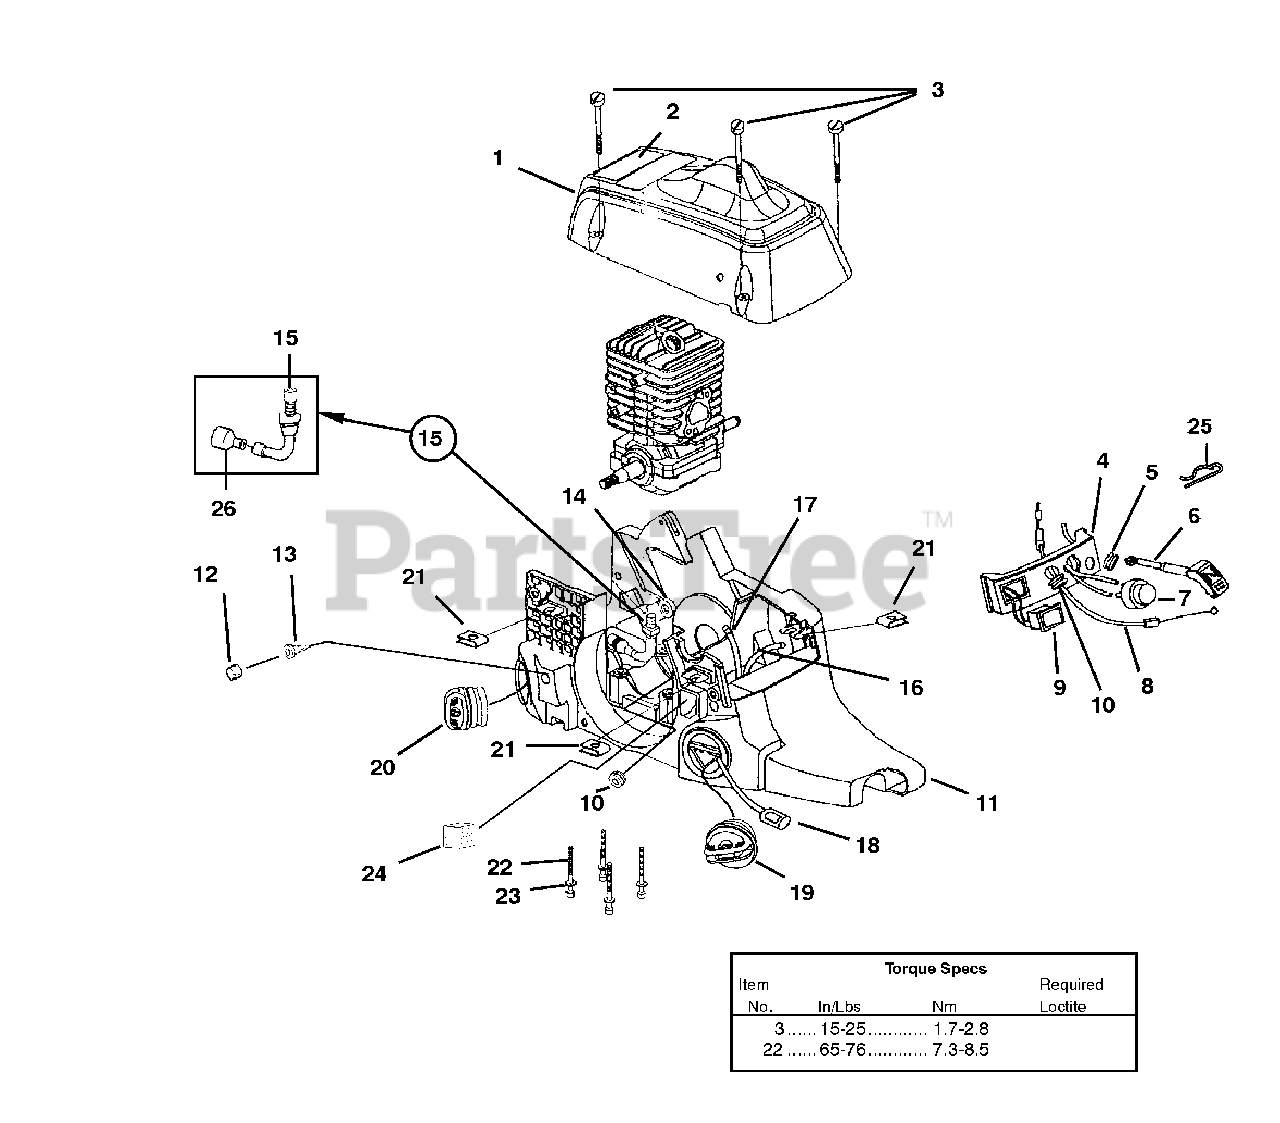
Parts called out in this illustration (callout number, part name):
1	Cylinder Cover Kit
2	Safety Decal
3	Screw-Slotted Pan Hd.
4	Control Panel
5	Grommet
6	Rod, Choke
7	Bulb, Air Purge
8	Throttle Cable
9	Switch, Rocker
10	Grommet - Split
11	Engine Housing
12	Element, Filter (Bronze)
13	Duck Bill Valve
14	Oil Outlet Grommet
15	Oil Intake Tube
16	Rubber Tubing (5 1/2")
17	Rubber Tubing (8 1/2")
18	Fuel Filter
19	Fuel Cap w/ Retainer
20	Oil Cap w/ Retainer
21	Speed Nut ("U-Type")
22	Screw, Cap-Socket Hd. (10-24 x 2")
23	Washer
24	Pre Filter
25	Spring Clip (Choke Rod)
26	Oil Filter
